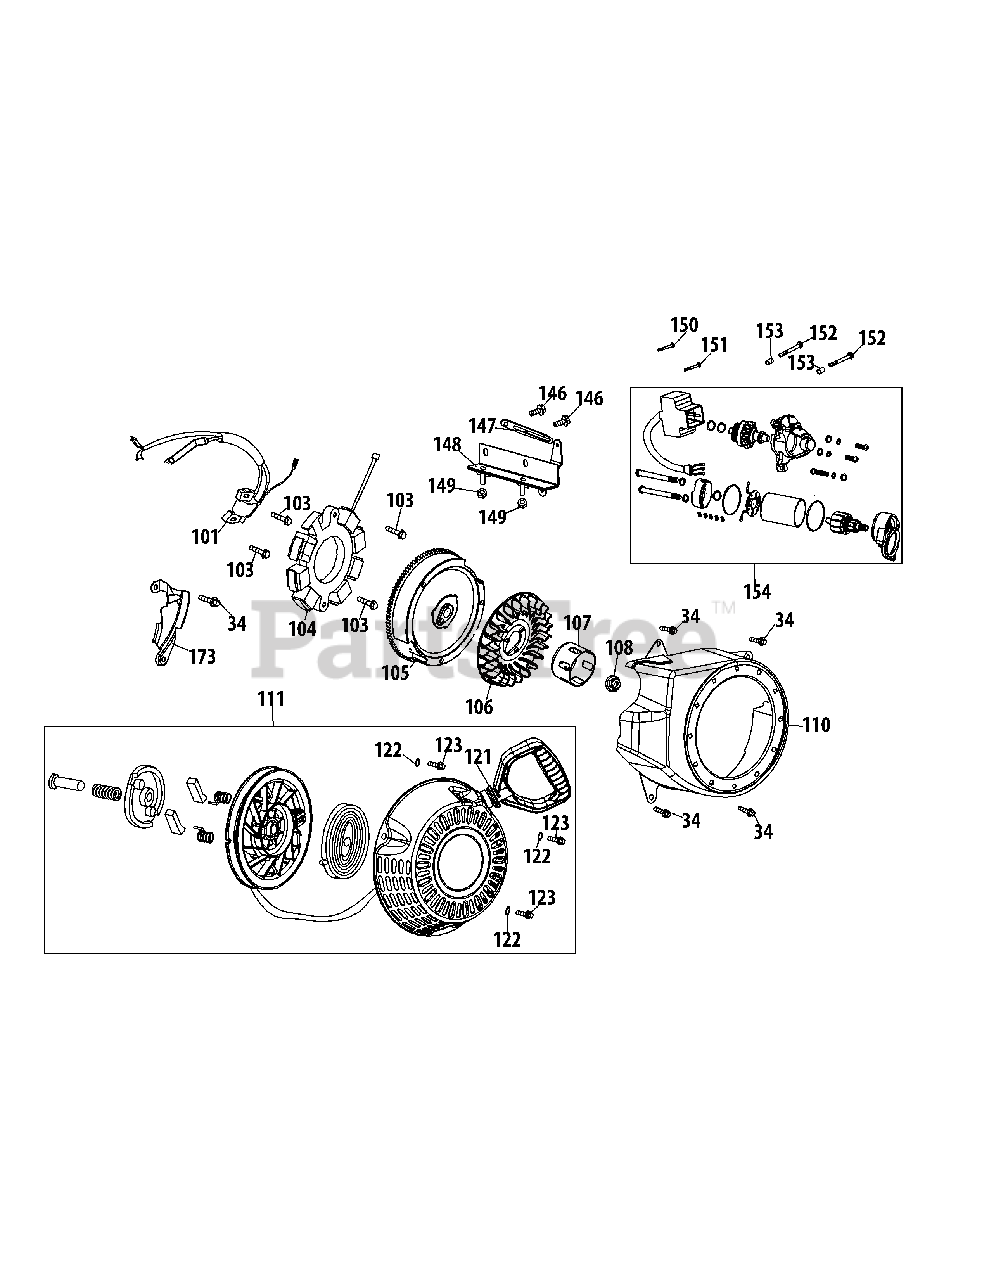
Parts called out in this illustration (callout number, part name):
34	Bolt M6×12
101	Ignition Coil Assembly
103	Bolt M6×25
104	Alternator Assembly
105	Flywheel
106	Cooling Fan
107	Starter Cup
108	Flywheel Nut, M14×1.5
110	Blower Housing
111	Recoil Starter Assembly
121	Starter Handle
122	Washer 6
123	Bolt M6×10
146	Bolt M6×10
147	Electric Starter Cord Retainer
148	Switch Housing Mounting Bracket
149	Nut, M6
150	Bolt M4×55
151	Bolt M4×60
152	Bolt M6×32
153	Dowel Pin 8×8
154	Electric Starter
154	120V E-Strt Plug Kit
173	Blower Housing Shield
